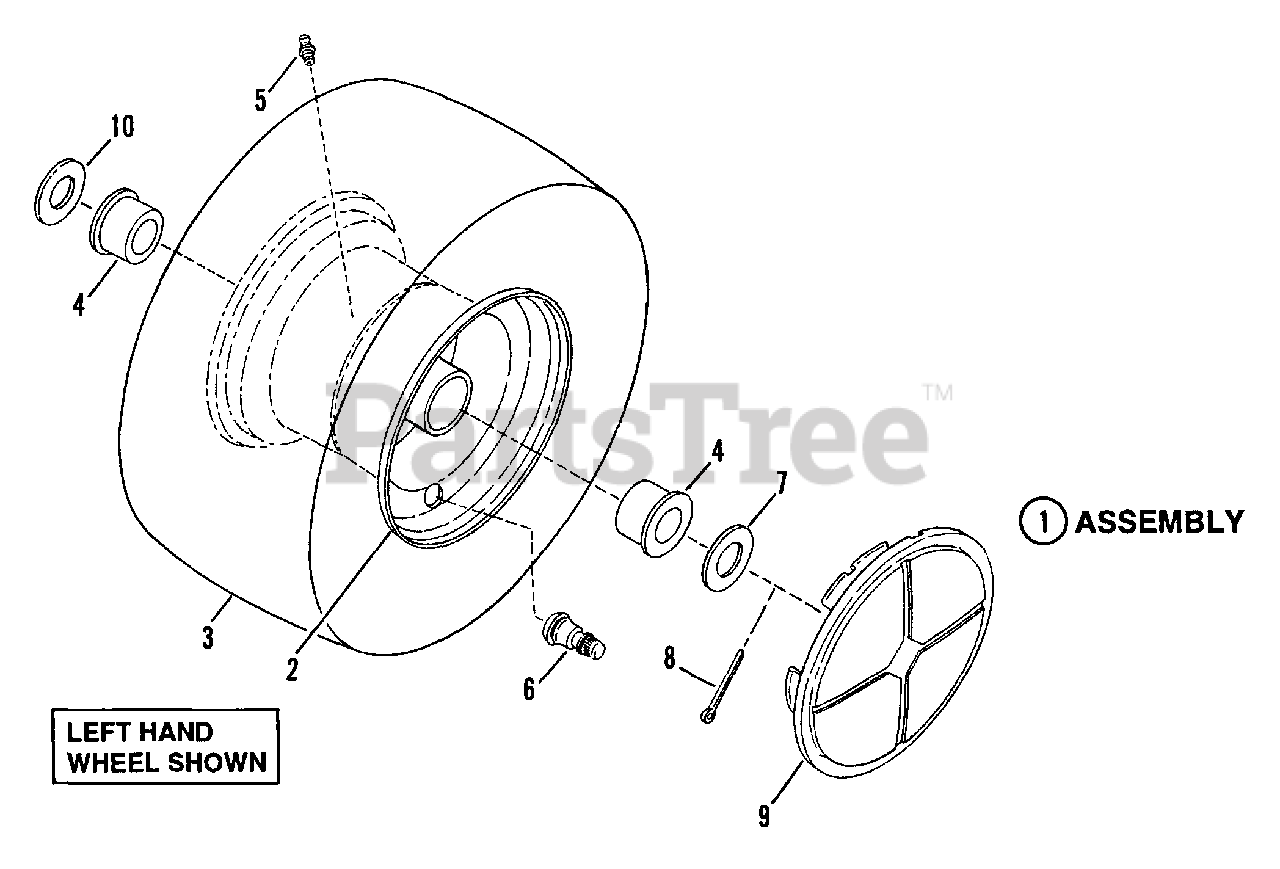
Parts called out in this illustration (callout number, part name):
1	ASSEMBLY, Front Tire & Rim
2	RIM, 6.00 x 4.50
3	TIRE, 15 x 6.00
4	BEARING, Wheel
5	FITTING, Lube 1/4-28 Tapered Thread
6	VALVE, Air (Snap-in)
7	WASHER, 49/64" I.D. x 1 1/2" O.D.
8	COTTER-PIN, 5/32 x 1"
9	WHEEL-COVER
10	WASHER, 25/32" x 1 1/2" O.D.
